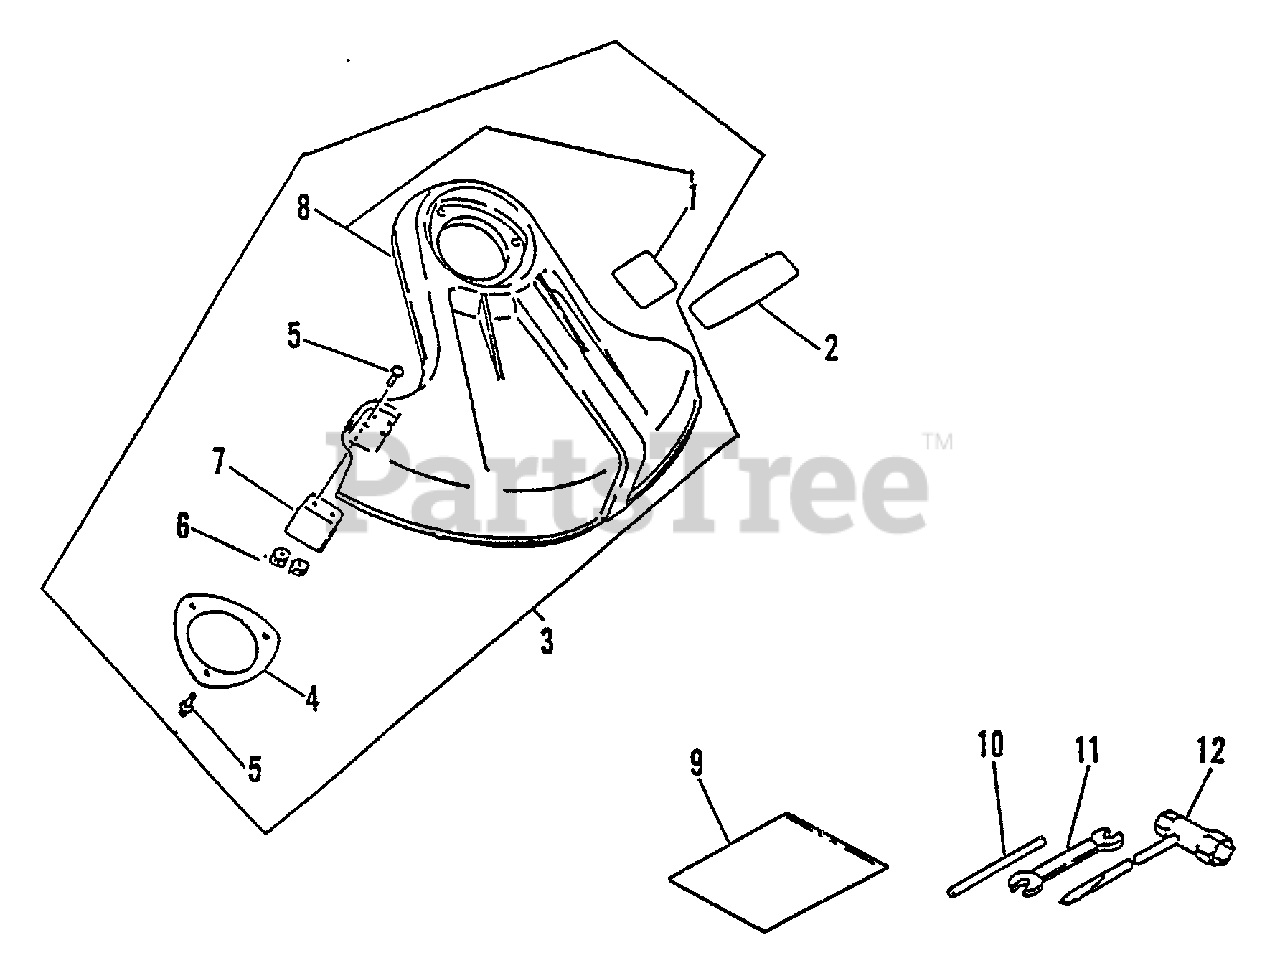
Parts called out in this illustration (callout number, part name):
1	LABEL - CAUTION
2	LABEL - LESCO
3	DEBRIS SHIELD KIT
4	PLATE, SHIELD
5	SCREW - 5X16
7	KNIFE, TRIMMER LINE
8	SHIELD, DEBRIS - PLASTIC
9	BAG, TOOL
10	LOCKING TOOL
11	SPANNER - 8X10mm
12	T-WRENCH - 17X19mm
